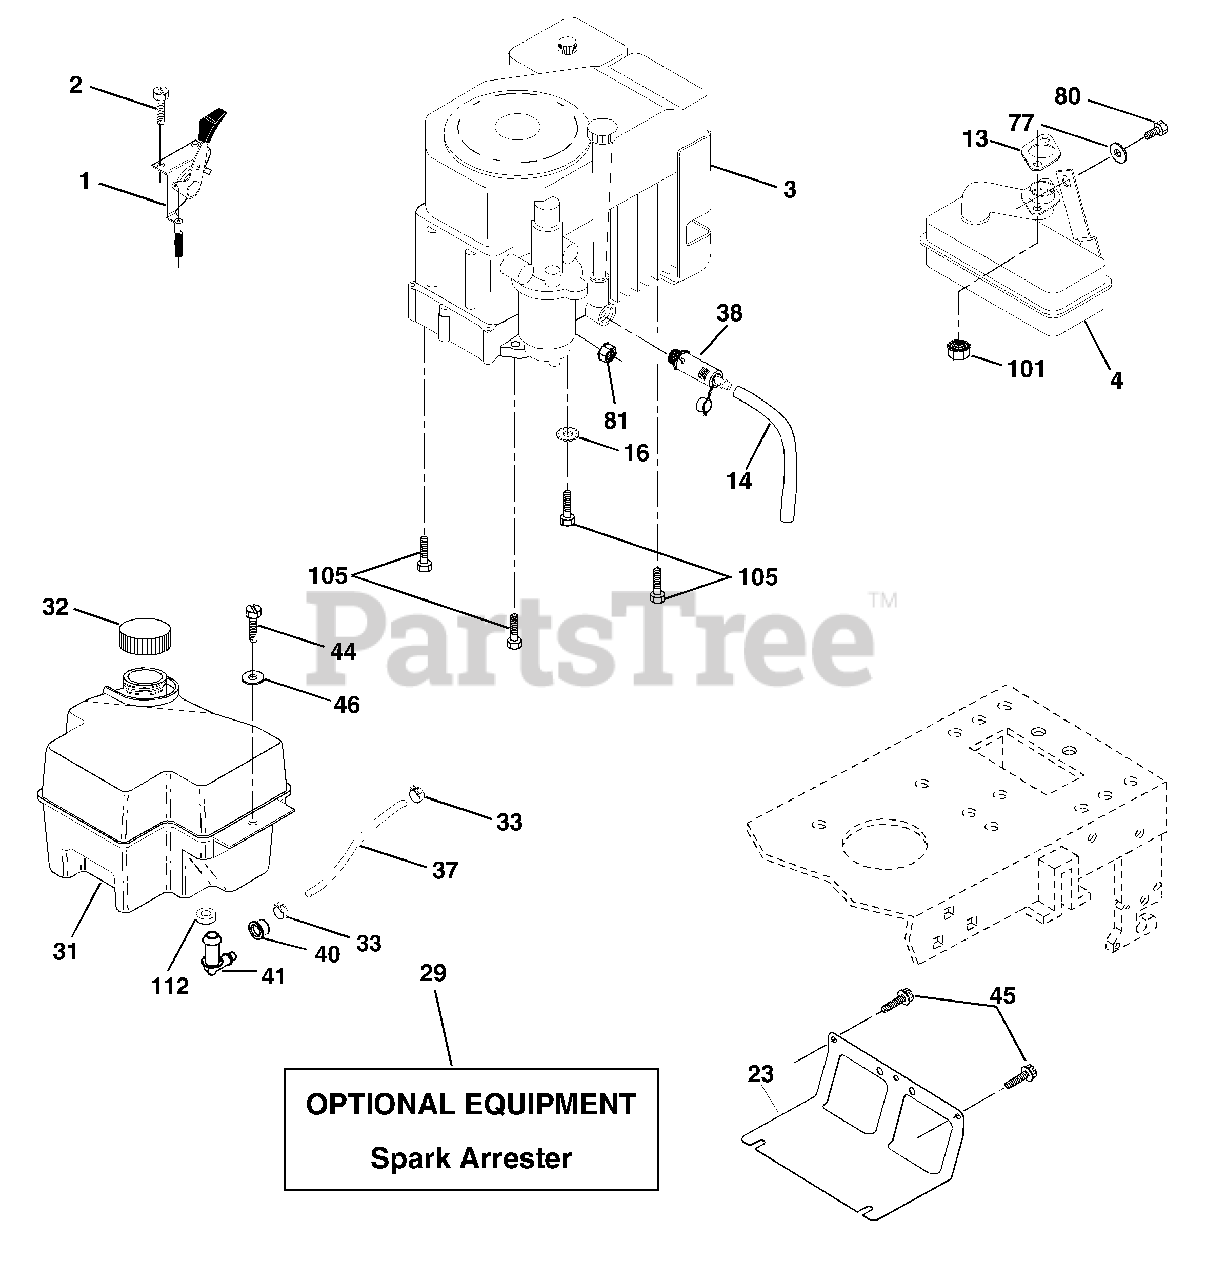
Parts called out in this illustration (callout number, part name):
1	Control Th/ch Flag Kohl. Dom.
2	Screw Hex Thd Cut 1/4-20x1/2
14	Tube Drain Oil Easy
16	Washer Lock Ext Tooth 3/8
23	Shield BRN/DBR Guard
29	Kit Spark Arrestor (Flat Scrn)
32	Cap Asm Fuel W/sym Vented
33	Clamp Hose Black
37	Line Fuel
38	Plug Drain Oil Easy
40	Bushing Snap Nyl Black Fuel Line
41	Stem Tank Fuel
44	Screw Hex Wsh Thdrol 1/4-20 x 3/4
45	Screw Hex Wsh Thdrol 3/8-16 x 3/4
46	Washer 9/32 x 7/8 x 16 Ga.
77	Washer 5/16 x 3/4 x 16 Ga.
80	Bolt Hex 5/16-18 Unc x 1/2
81	Nut Keps Hex 1/4-20 Unc
101	Nut Flange M8-1.25
105	Screw 3/8-16 x 1
112	Bushing
